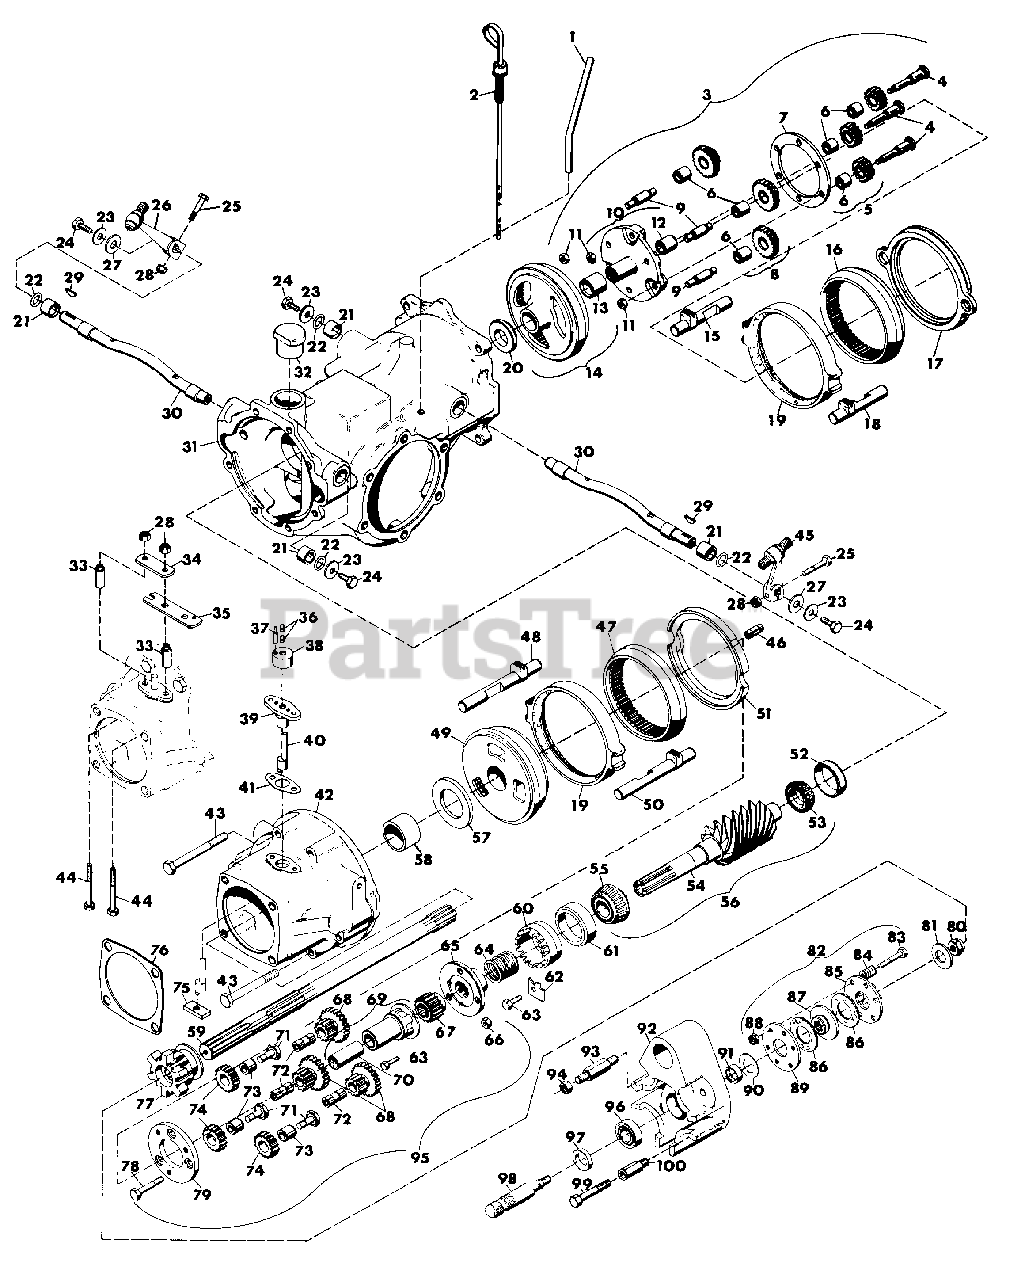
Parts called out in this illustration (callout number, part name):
1	GUIDE, DIPSTICK
2	ASSEMBLY, DIPSTICK
3	ASSEMBLY, HI-LO PLANETARY
4	BOLT, ORBIT GEAR
5	ASSEMBLY, EXTERNAL ORBIT GEAR
6	BUSHING, .501X.627X.495
7	SPACER, PIN
8	ASSEMBLY, INTERNAL ORBIT GEAR
9	PIN, HI-LO ORBIT GEAR
10	ASSEMBLY, PLANET GEAR CARRIER
11	NUT, LOCK 5/16-18 L.H. THD.
12	BUSHING, .737X.877X.682
13	BUSHING, 1.231X1.502X1.312
14	ASSEMBLY, RING GEAR AND BUSHING
15	ROD, REAR CLUTCH SLIDE L.H.
16	GEAR, REAR RING
17	SPACER, REAR
18	ROD, REAR CLUTCH SLIDE R.H.
19	ASSEMBLY, CLUTCH CUP
20	PLATE, REAR THRUST
21	BUSHING, .750X1.002X.625
22	O-RING, .750X1.00
23	WASHER, FLAT .265X1.250X.063
24	BOLT, HEX 1/4-20X.50
25	BOLT, HEX 5/16-18X2.00
26	ASSEMBLY, FWD-REV LEVER
27	WASHER, FLAT .812X1.496X.134
28	NUT, LOCK 5/16-18
29	KEY, WOODRUFF .125X.625 HARD #5
30	SHAFT, ACTUATING
31	CHASSIS
32	PLUG, OIL FILLER
33	SPACER, SHIPPER SHAFT GUIDE
34	SPACER, STRAP
35	ARM, SHIFTER
36	SCREW, SET 3/8-16X.25 HSCKT
37	PIN, SPRING .25X.75
38	BODY, SHIPPER SHAFT
39	GUIDE, SHIPPER SHAFT
40	SHAFT, SHIPPER
41	GASKET, SHIPPER SHAFT
42	ASSEMBLY, ADVANCE CASTING
43	BOLT, HEX 5/16-18X3.25 GR. 8
44	BOLT, HEX 5/16-18X2.25
45	ASSEMBLY, HI-LO LEVER
46	PIN, ROLL
47	GEAR, INTERNAL
48	ROD, CLUTCH SLIDE L.H.
49	CONE, REVERSE GEAR
50	ROD, CLUTCH SLIDE R.H.
51	CUP, GEAR
52	CUP, ROLLER BEARING
53	CONE, ROLLER BEARING
54	WELDMENT, 6-LEAD WORM - 2 SPEED
54	WELDMENT, 8-LEAD WORM - 4 SPEED
55	CONE, ROLLER BEARING
56	WELDED WORM SHAFT ASSEMBLY, 6-LEAD
56	WELDED WORM SHAFT ASSEMBLY, 8-LEAD
57	DISC, FRICTION
58	BEARING
59	SHAFT, PINION
60	NUT, BEARING ADJUSTMENT
61	CUP, ROLLER BEARING
62	NUT, ADJUSTMENT
63	BOLT, HEX 1/4-20X.625
64	SPACER, SPRING PIN PLATE
65	PLATE, FRONT PIN
66	NUT, HEX 1/4-20
67	GEAR, SUN PINION
68	GEAR, ORBIT
69	ASSEMBLY, QUILL AND BUSHING
70	BUSHING, .875X1.000X2
71	BOLT, REVERSE IDLER
72	PIN, FWD-REV ORBIT GEAR
73	BUSHING, REVERSE IDLER
74	GEAR, REVERSE IDLER SPUR
75	BLOCK, TRUNNION
76	GASKET, ATTACHMENT
77	DOG, ATTACHMENT
78	BOLT, SPACER
79	SPACER, FRONT PIN
80	NUT, LOCK 5/8-24
81	WASHER, FLAT .656X1.312X.095
82	ASSEMBLY, CLUTCH ATTACHMENT
83	BOLT, HEX 5/16-24X1.75
84	SPRING, COMP. .75X2200 RATE
85	PLATE, DOG
86	WASHER, FRICTION
87	PLATE, DRIVE
88	NUT, JAM 5/16-24
89	PLATE, BACK
90	BEARING, THRUST 1.012X1.750X.125
91	BEARING, NEEDLE 1.000X1.250X2.000
92	ADAPTOR, QUICK HITCH
93	STUD, QUICK HITCH
94	NUT, HEX 1/2-13
95	ASSEMBLY, FWD-REV PLANETARY
96	BEARING, BALL
97	RING, STEEL RETAINING .978X1.500X3.00
98	SHAFT, QUICK HITCH
99	BOLT, HEX 1/2-13X1.00
100	STUD, QUICK HITCH
